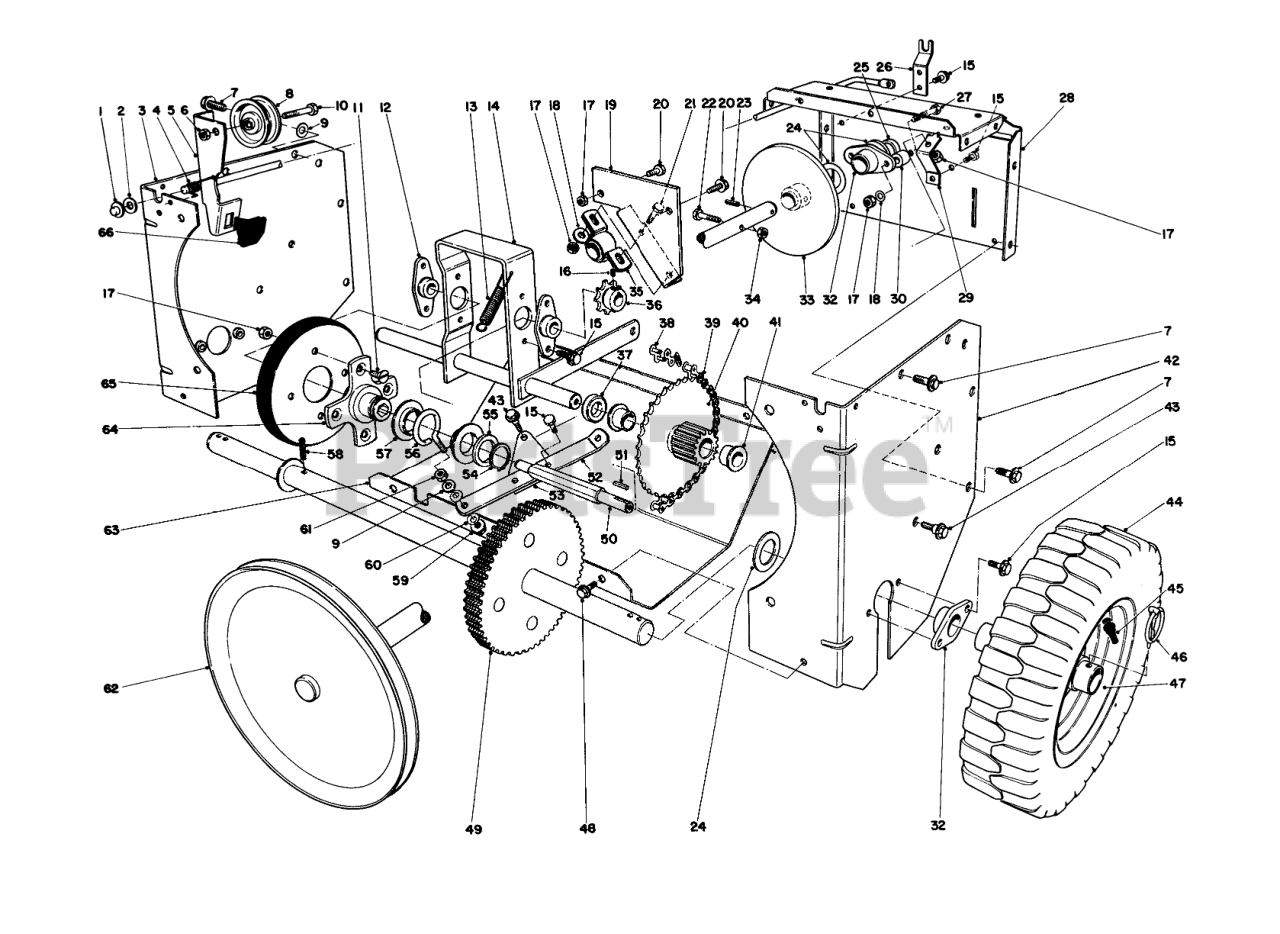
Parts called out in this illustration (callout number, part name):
1	PUSH NUT
2	WASHER-FLAT
3	RH TRACT SIDE PLT R
4	TORSION CLUTCH SPRING
5	Clutch Rod (Incl. Ref. #66)
6	NUT-LOCK, NI
7	SCREW-HHFTF
8	PULLEY-IDLER
9	WASHER-FLAT
10	SCREW-HH
11	5/16-18X5/8 FLT HD MS
12	BEARING-WHEEL, FRICTION
13	TENSION SPRING
14	PIVOT SHAFT WA B
15	SCREW-HWHTF
16	SCREW-HSH
17	NUT-LOCK, NI
18	WASHER-PLAIN
19	SHAFT SUPT BRKT B
20	SCREW-HH
21	SCREW-HH
22	SCREW-HH
23	PIN-ROLL, SLOTTED
24	WASHER
25	DRIVE SHAFT SPACER
26	CLUTCH ROD SUPPORT
27	SCREW-HH
28	CENTER FRAME R
29	PIVOT BRACKET
30	BRG STANDOFF
32	AXLE BEARING
33	FRICTION PLT WA
34	NUT-LOCK, CONE
35	PILLOW BLOCK BRG
36	SPROCKET
37	COSHAFT SPACER
38	LINK-CONNECTING
39	ROLLER-CHAIN
40	Gear & Bushing (Incl. Ref. #41)
41	BUSHING
42	LH TRACT SIDE PLT R
43	SHOULDER SCREW
44	Tire
45	STEM-VALVE
46	PIN-LYNCH
47	Wheel
48	SCREW-HWH
49	AXLE & GEAR WA
50	FRICTION WHL SHAFT
52	SHIFT LINKAGE
53	PIVOT PLATE
54	RING-RETAINING
55	WASHER-THRUST
56	SLIDER RING COLLAR
57	SLIDER RING
58	PIN-ROLL, SLOTTED
59	NUT-LOCK, FLANGE
60	WASHER-SPRING
61	NUT-LOCK
62	PULLEY/SHFT WA
63	LOWER SHIELD R
64	TRACTION DISC HUB
65	FRICTION WHEEL
66	Brake Pad
